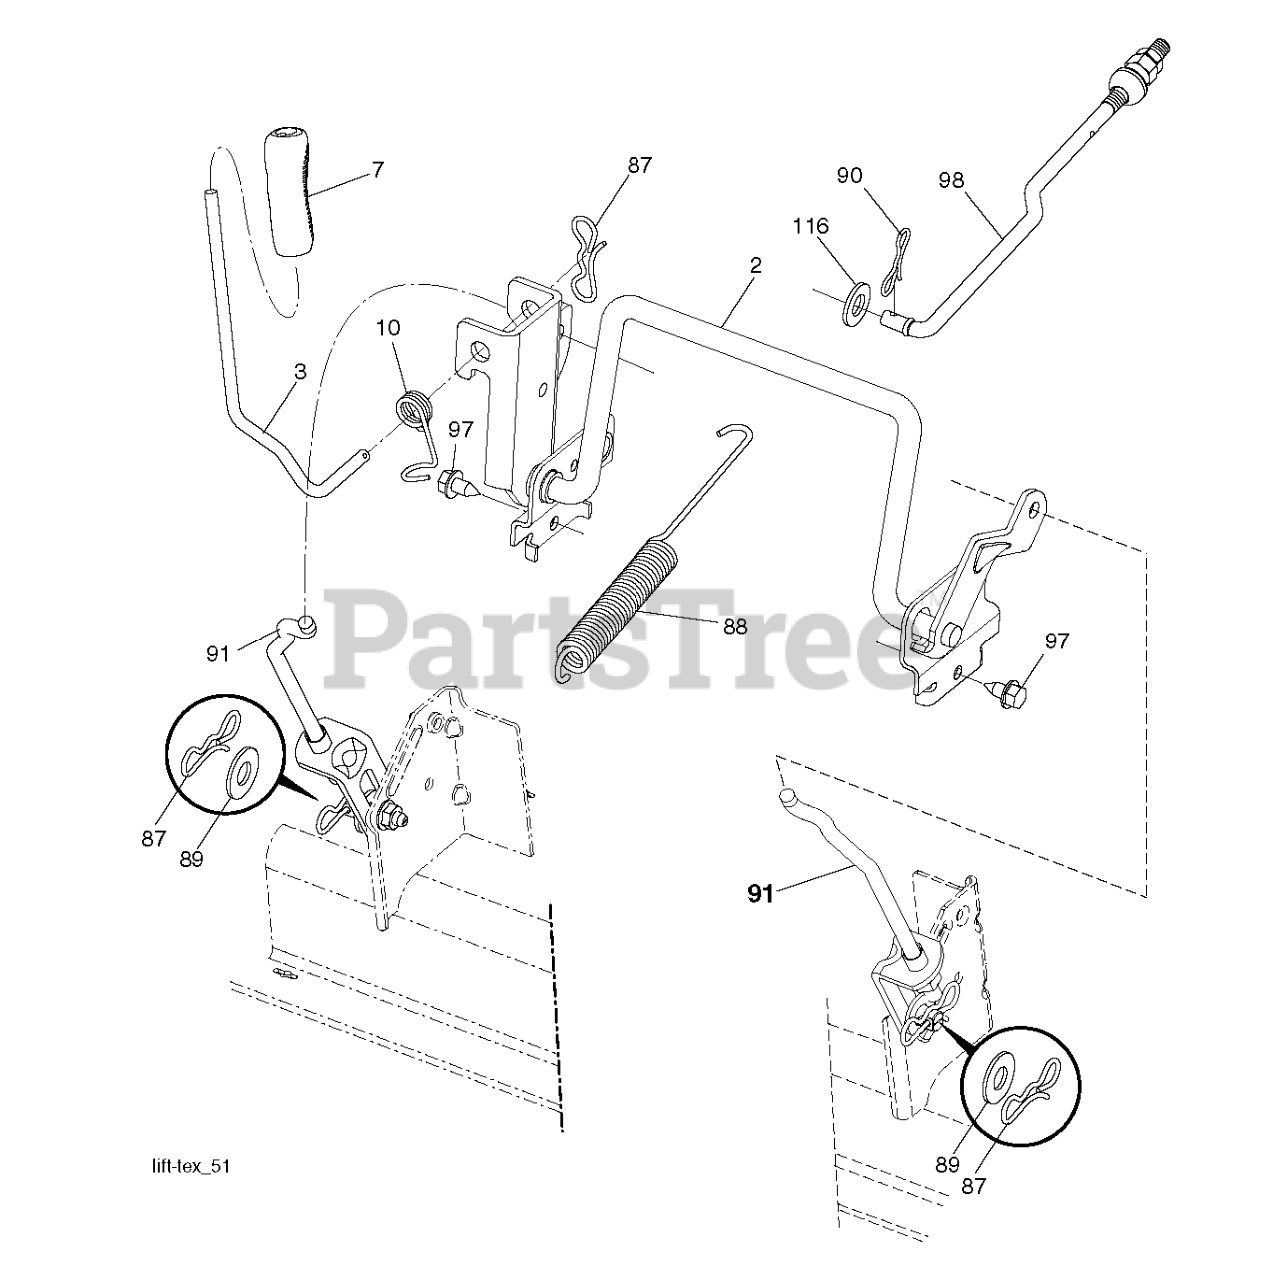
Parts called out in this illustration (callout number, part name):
2	SHAFT LIFT DECK WELD
7	GRIP.HANDLE.LIFT.PVC.BLACK
10	SPRING.TORSION.LIFT.HANDLE
87	PIN.COTTER.7/16.BOW TI.
88	SPRING.DK.LIFT.97/107.TXCRDII
89	WASHER.CLEAR.ZINC
90	PIN.COTTER.5/16.BOW TI
